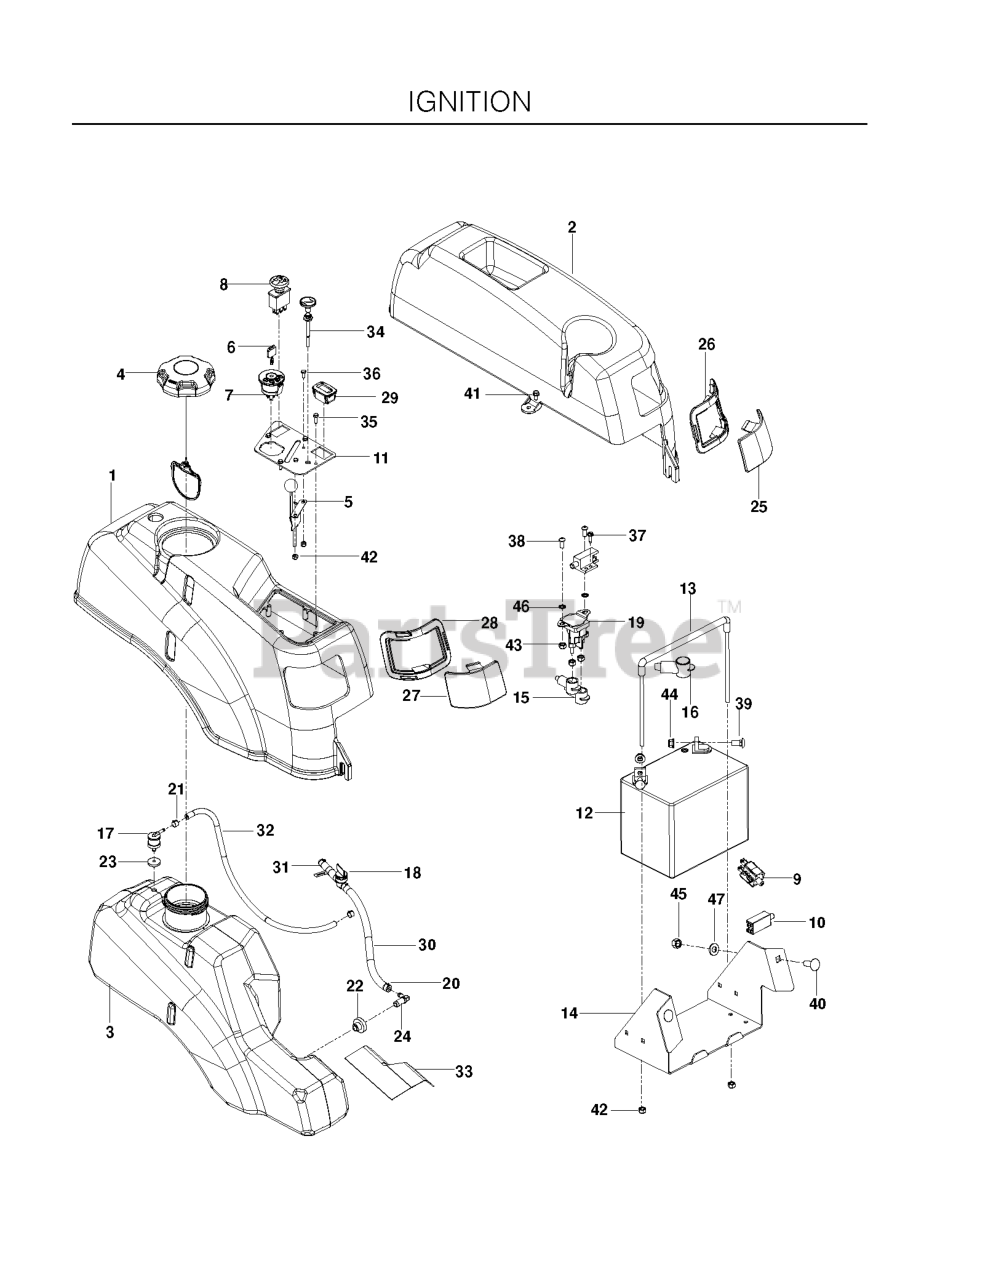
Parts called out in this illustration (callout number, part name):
1	FENDER, RT, GRAY
2	FENDER, LT
3	TANK, FUEL, RT-EPA
4	CAP, FUEL
5	THROTTLE CABLE
6	KEY
7	RP IGNITION SWITCH
8	RP.SWITCH, BLADE
9	SWITCH, BRAKE 3P
10	SWITCH, INTERLOCK
11	PLATE.CONTROL.CONSOLE.BLACK
12	BATTERY, 12 V 330 AMP
13	BATTERY TIE DOWN ASSEMBLY
14	BOX, BATTERY, BLACK
15	TERMINAL COVER-SM
17	VALVE.FUEL.CHECK
18	FUEL VALVE
20	HOSE CLAMP
21	CLAMP, HOSE
22	RUBBER GROMMET
23	GROMMET, CHECK VALVE
24	STEM, FUEL TANK
25	LENS, COLORED LEFT
26	LEFT HEADLIGHT RIM GREY
27	LENS, COLORED RIGHT
28	RT HEADLIGHT RIM GREY
29	HOUR METER
30	GAS LINE 10"
31	FUEL LINE 3"
32	HOSE, FUEL, 3/16" X 17-1/4"
33	SHIELD, HEAT
34	CHOKE CONTROL, COMPLETE
35	SCR #10-12X3/4 HEX WAS HD ZD
36	HCS #10-24 X 1/2
37	SCREW #10 X 1/2 SELF TAPPING
38	SCR 1/4-20 X 5/8 BTN SKT HD ZD
39	BOLT 5/16C X 3/4" CARRIAGE
40	RHSNB 3/8C X 1
41	BOLT 1/4-20 X 1/2 HWST
42	NUT 10-24 NYLOC
43	NUT.1/4-20.HEX.NYLOC.ZD
44	5/16-18 NYLOC FLANGE NUT
45	NUT 3/8-16 NYLOC
46	WASHER 1/4 INT TOOTH
47	WASHER 3/8 SAE FLAT
